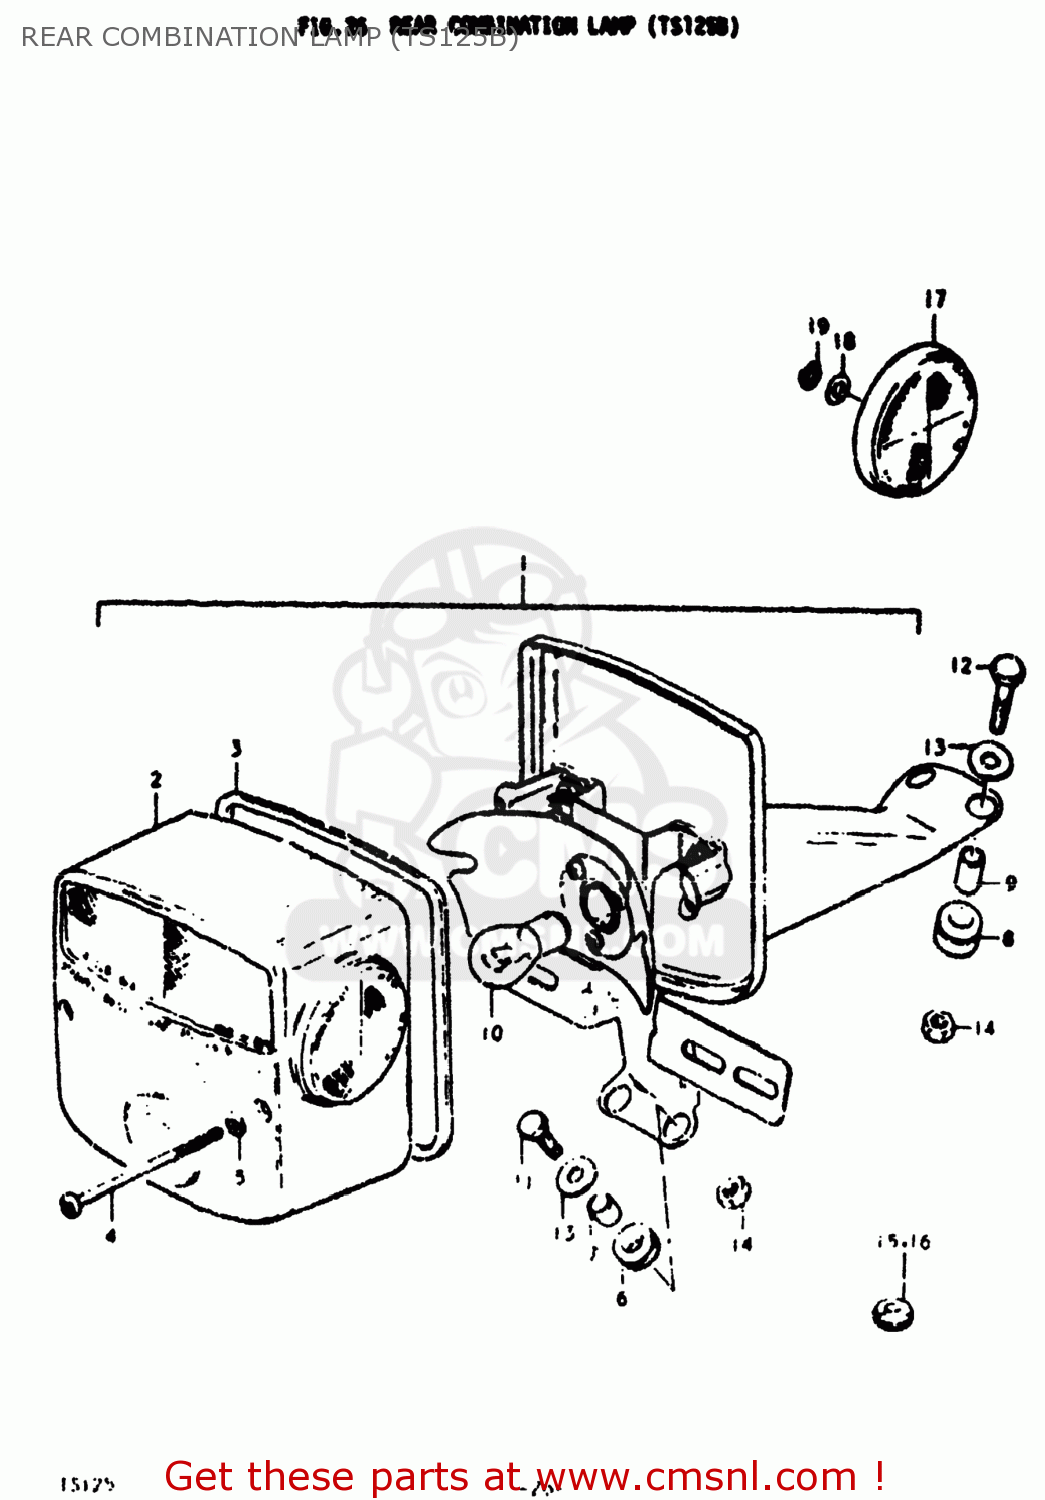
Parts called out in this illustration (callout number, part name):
1	LAMP ASSEMBLY,REAR COMBINATION
2	LENS
3	GASKET (NAS)
4	SCREW
5	GASKET (NAS)
6	CUSHION
7	SPACER,REAR COMBINATION LAMP
8	CUSHION
9	SPACER,REAR COMBINATION LAMP
10	BULB(6V32/3CP,STANLEY)
11	BOLT
12	BOLT
13	WASHER (6.5X20X1.2)
14	NUT
15	GROMMET
16	GROMMET
17	REFLEX REFLECTOR,FR
18	WASHER
19	LOCK WASHER
